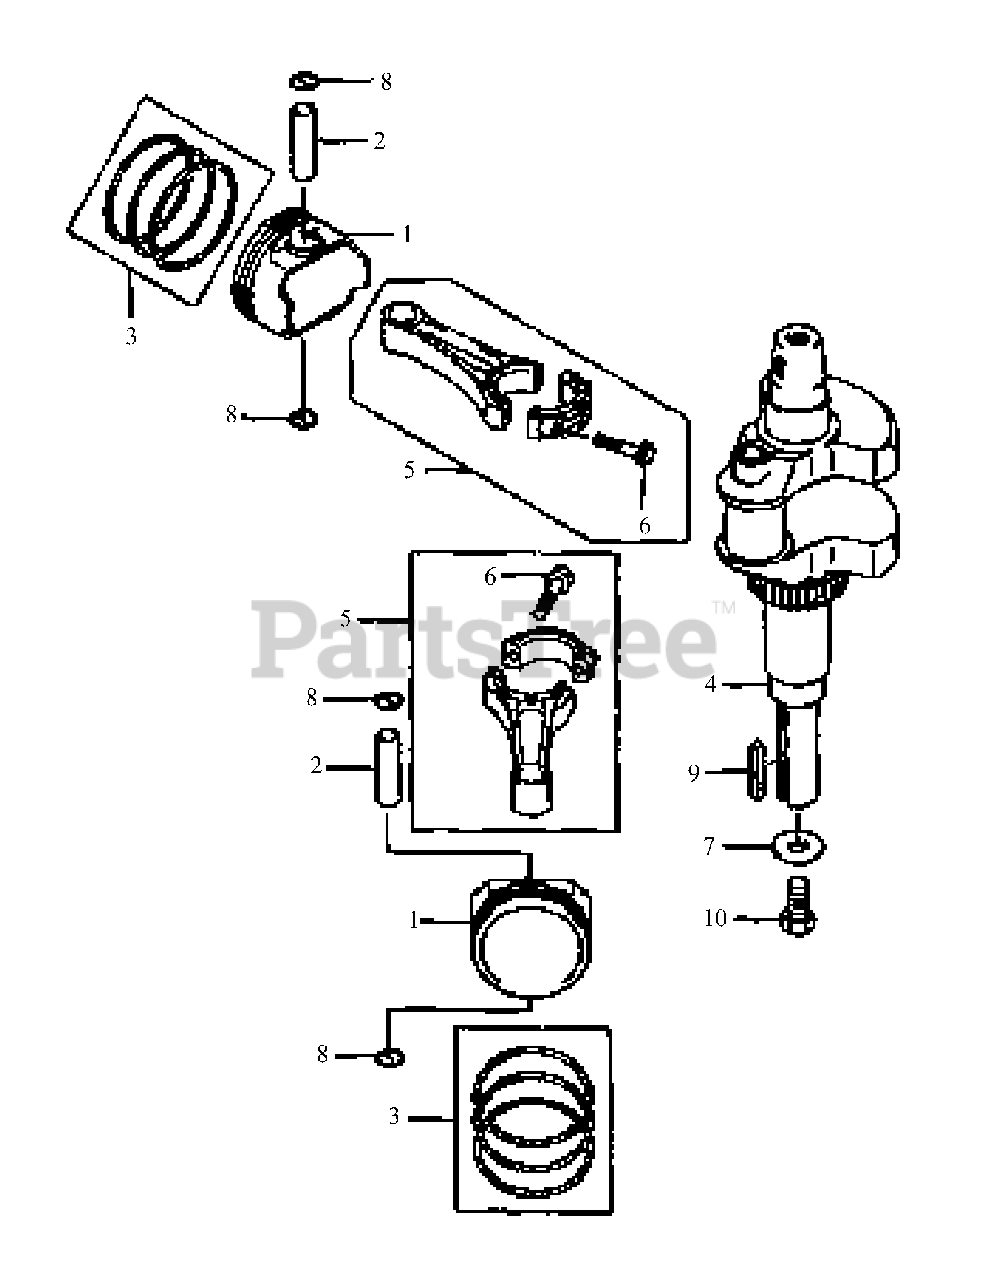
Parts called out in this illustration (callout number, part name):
1	Piston-Engine
3	Ring-Set-Piston
4	Crankshaft Complete
5	Rod-Connecting
7	Washer,12.5x32x3.2
10	Bolt,7/16-20unf
